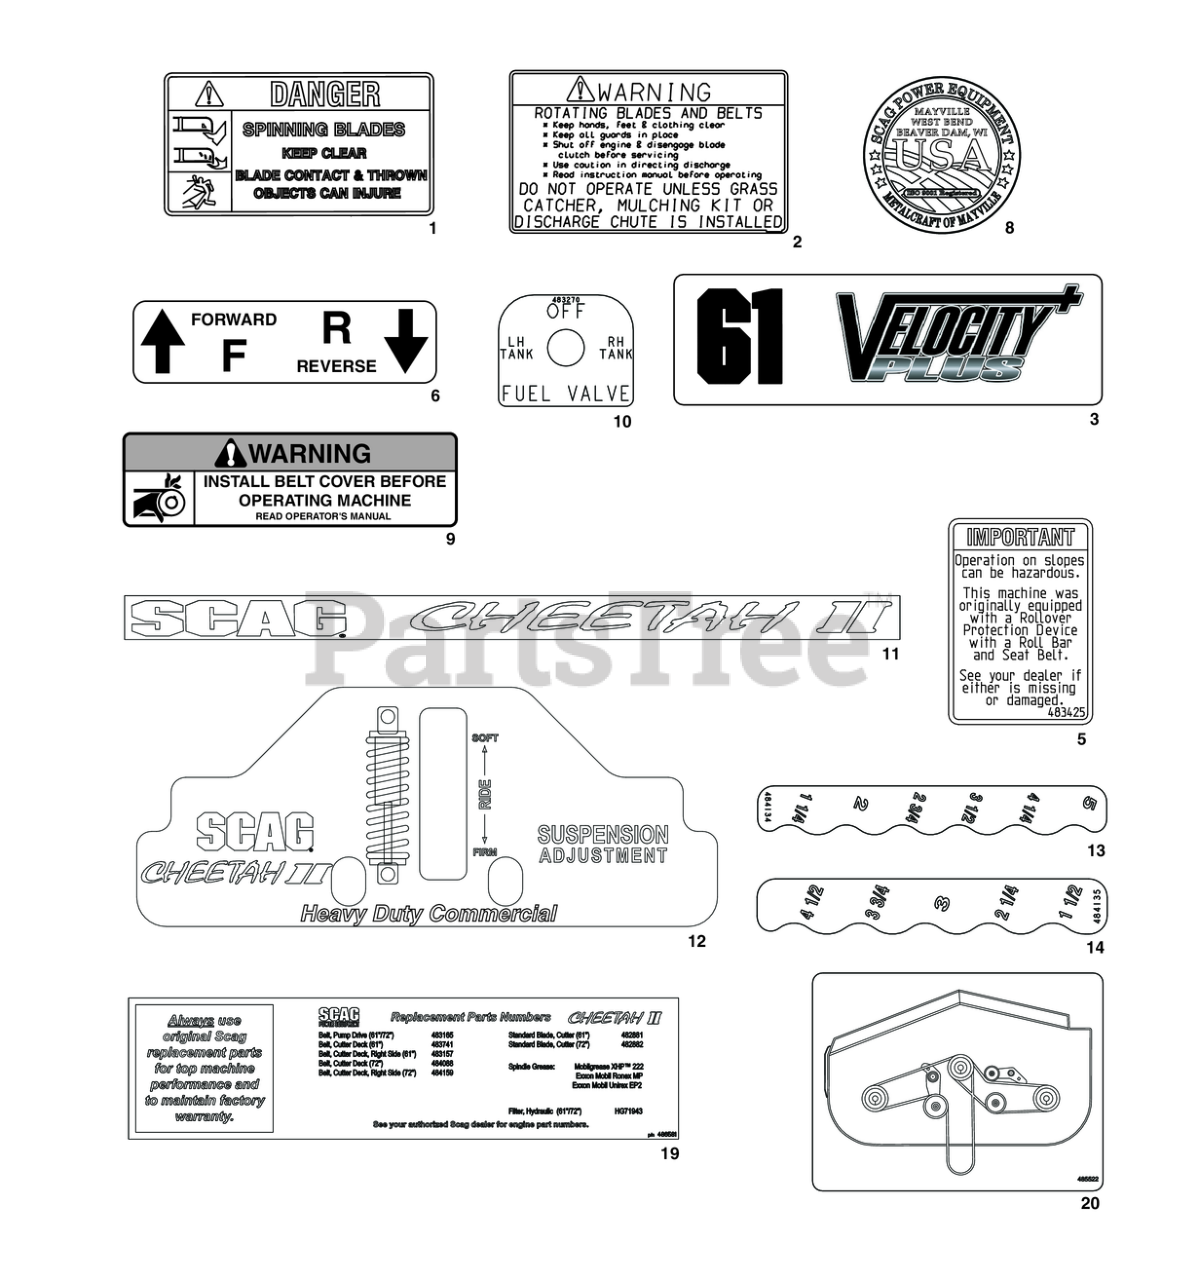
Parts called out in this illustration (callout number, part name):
1	Decal, Danger-Spinning Blades
2	Decal, Warning - Rotating Blades
3	DECAL, VELOCITY PLUS - 61
3	Decal, Velocity Plus - 61RD
3	Decal, 72" Velocity Plus
5	Decal, ROPS
6	Decal, Traction Control
8	Decal, Metalcraft - USA
9	Decal, Warning - Belt Cover
10	Decal, Fuel Shut Off
11	Decal, Scag Cheetah II
12	Decal, Suspension Adjustment
13	Decal, Deck Height - LH
14	Decal, Deck Height - RH
19	Decal, SCZII Replacement Parts
20	Decal, SCZII Belt Routing 61RD
